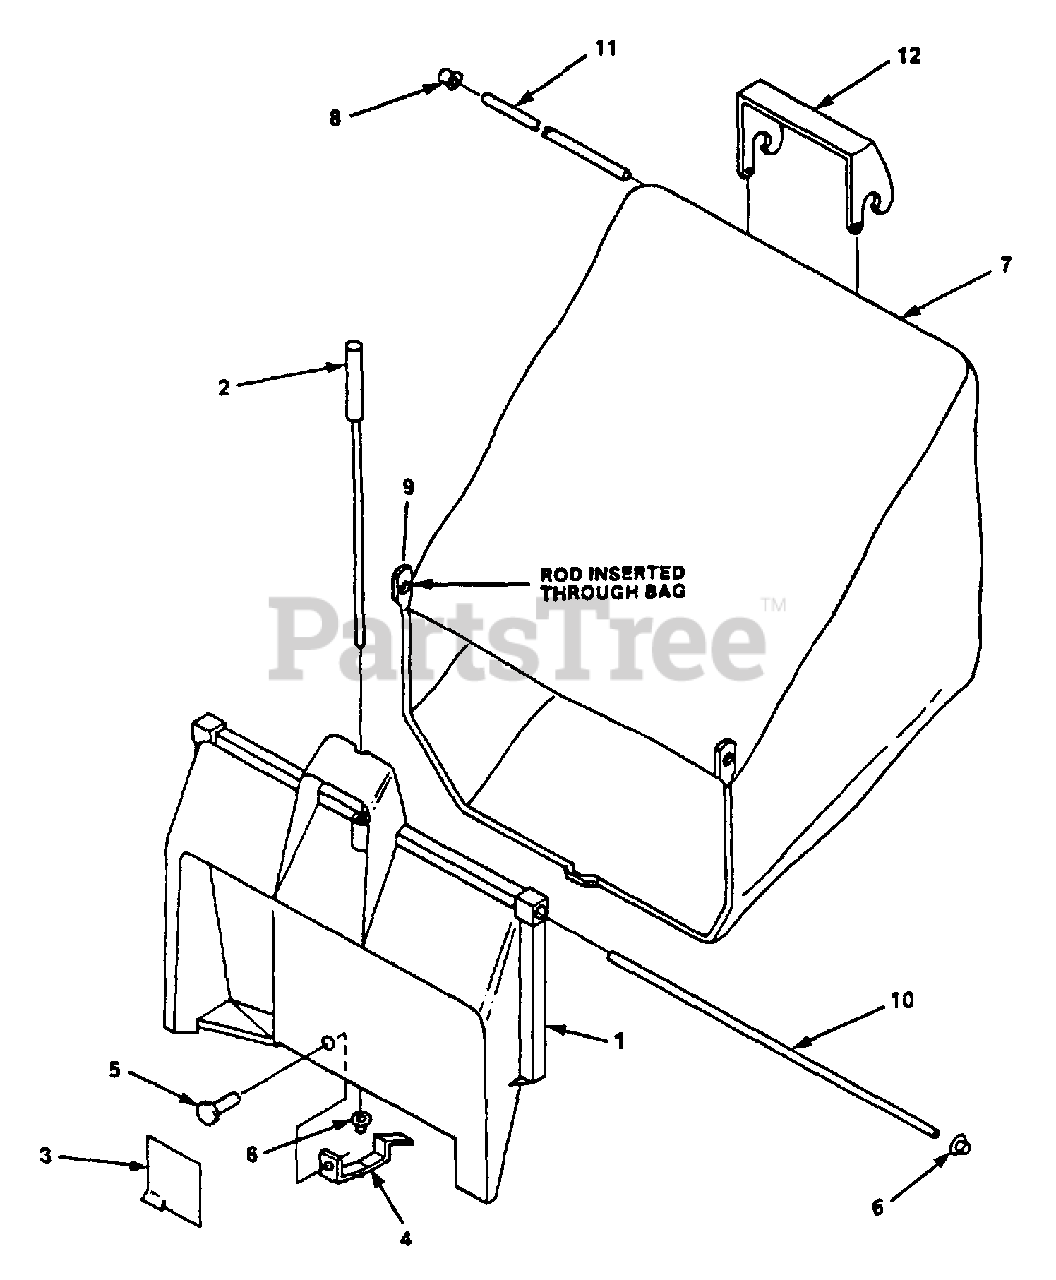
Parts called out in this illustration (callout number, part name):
1	ADAPTER, BAG
2	ROD, LATCH RELEASE
3	DEFLECTOR
4	LATCH
5	RIVET
6	NUT, PAL
7	BAG, GRASS
8	END, ROD
9	ROD, BAG SUPPORT
10	ROD, BAG HINGE
11	ROD, UPPER BAG
12	HANDLE
